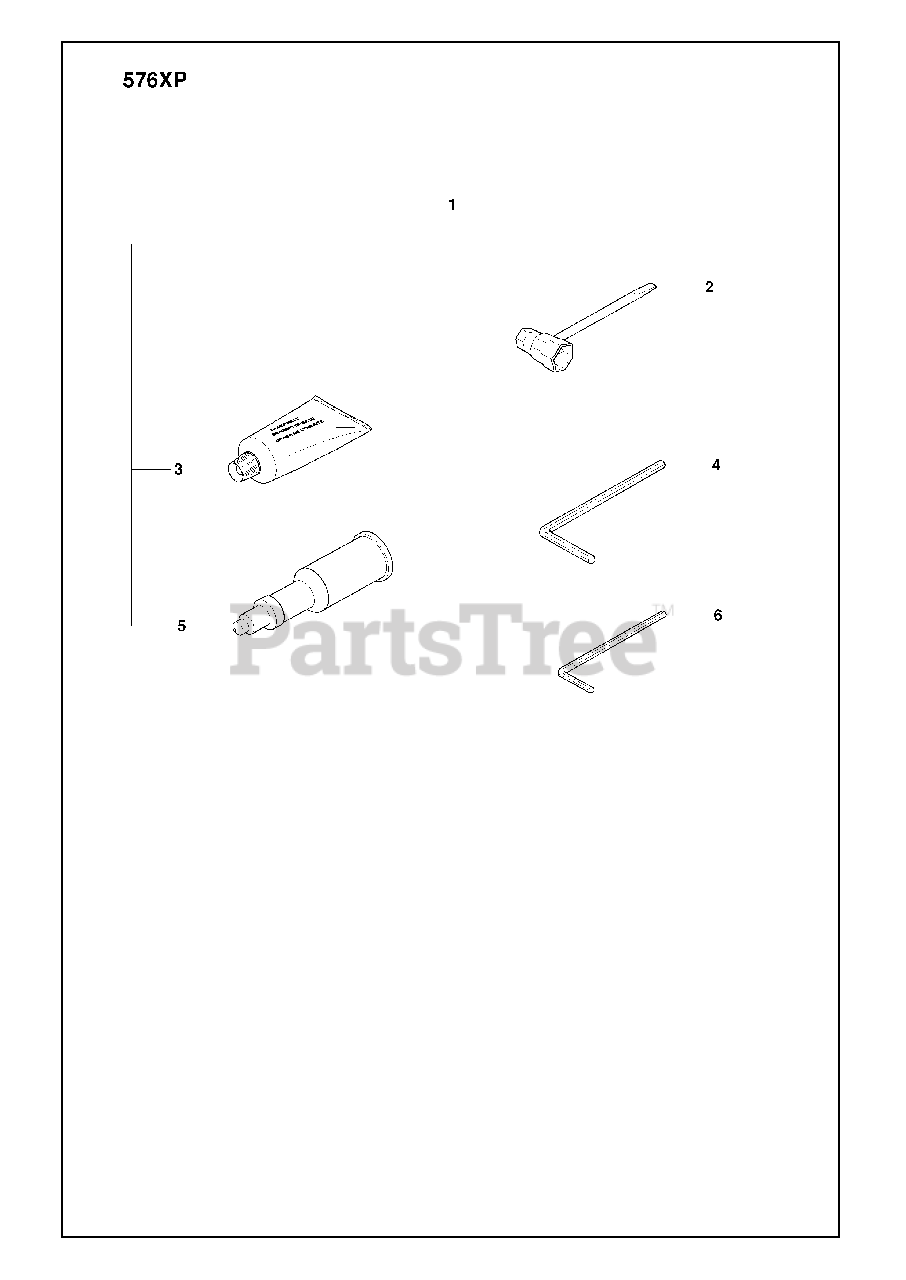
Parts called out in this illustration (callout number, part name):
1	TOOL KIT
2	COMBI TOOL
3	GREASE
5	Grease Gun
